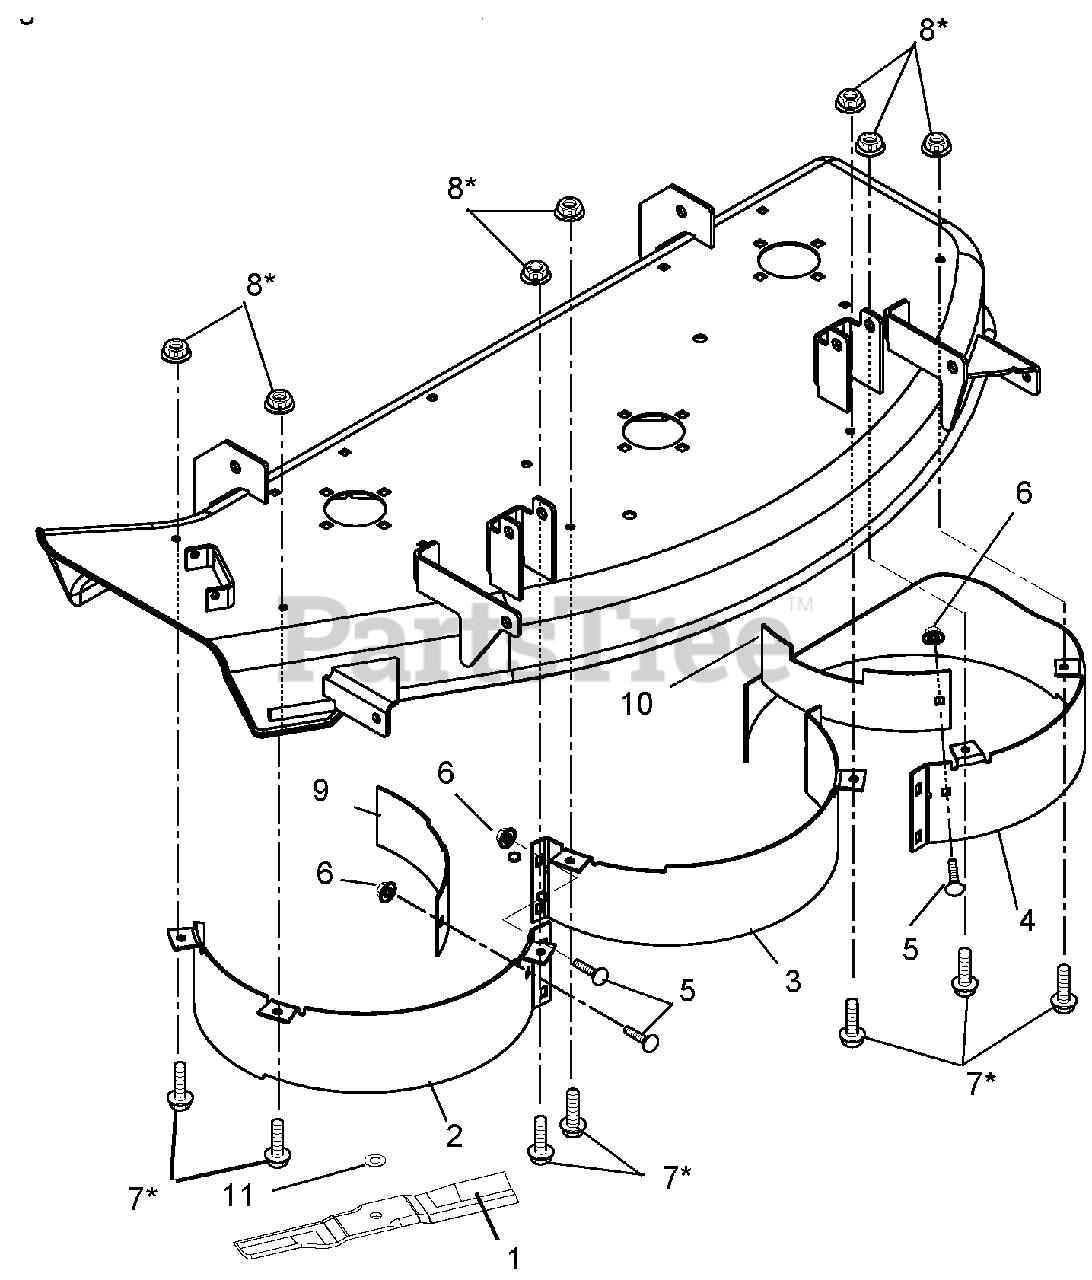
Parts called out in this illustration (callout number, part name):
1	BLADE, MULCH 13.88
2	MULCH BAFFLE, 40" ZOOM RIGHT
3	MULCH BAFFLE, 40" ZOOM CENTER
4	MULCH BAFFLE, 40" ZOOM LEFT
5	@BLT-RDHDSQNK .31-18X1.00 G5YZ
6	NUT-LK-TOP-FLG .31-18 YWZC
7	@BLT-HEX .31-18X.75 GR5 YWZC
8	NUT-SPNLK-FLG .312-18 YWZC
9	BAFFLE, 40" ZOOM CHAMBER SEPAR
10	SEPARATOR, 40" CHAMBER
11	@WSHR-FL-STL.688X1.75X.134 YWZ
